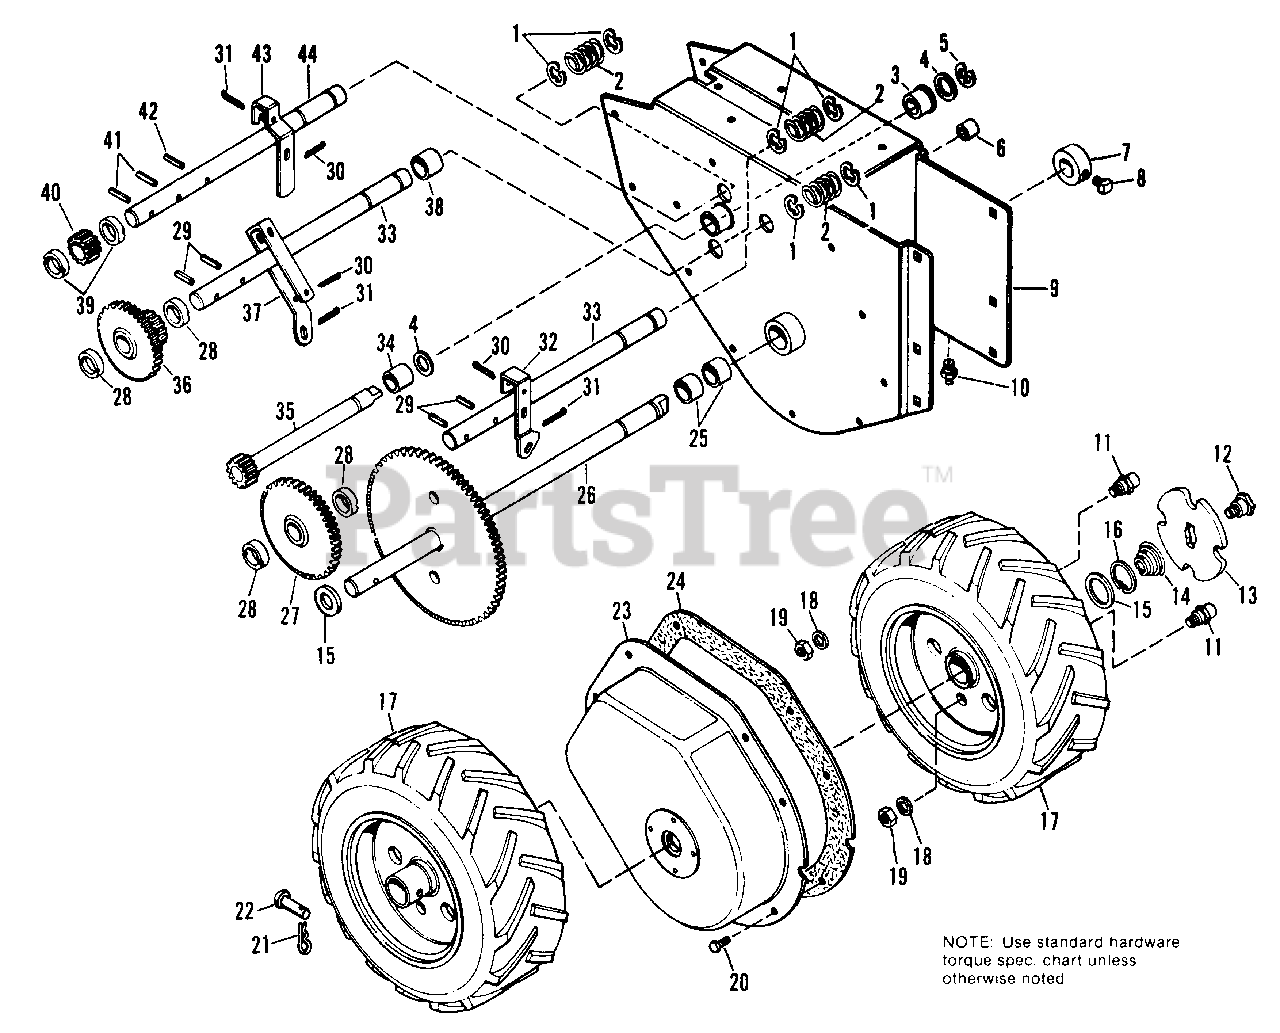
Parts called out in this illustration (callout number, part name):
1	RING, Retaining
3	BEARING, Bronze
5	RING, Retaining
7	COLLAR, Set
8	SETSCREW, 5/16-18 x 3/8
9	ENGINE BASE & FRAME ASSY.
10	FITTING, Grease
12	BOLT, Shoulder
16	RING, Retaining
17	WHEEL & TIRE ASSY.
18	WASHER, Plain, 5/16
19	LOCKNUT, Hex, 3/8-16
20	SCREW, Taptite, 1/4-20 x 3/10
21	CLIP, Pin
22	PIN
23	CASE ASSY., Gear
26	AXLE & GEAR ASSY.
27	GEAR & BEARING ASSY., Lower
28	COLLAR, Thrust
29	PIN, Roll, 1/8 x 1
30	PIN, Cotter, 3/16 x 1
31	PIN, Cotter, 3/32 x 3/4
32	LINK, Shift, Lower
33	SHAFT, Intermediate
34	BEARING, Bronze
35	SHAFT ASSY., Gear
36	GEAR & BEARING ASSY., High
37	LINK, Shift, High
39	COLLAR, Thrust
40	PINION, Reverse
41	PIN, Roll, 1/8 x 3/4
42	PIN, Roll, 5/32 x 1
43	LINK, Shift, Reverse
44	SHAFT, Reverse
